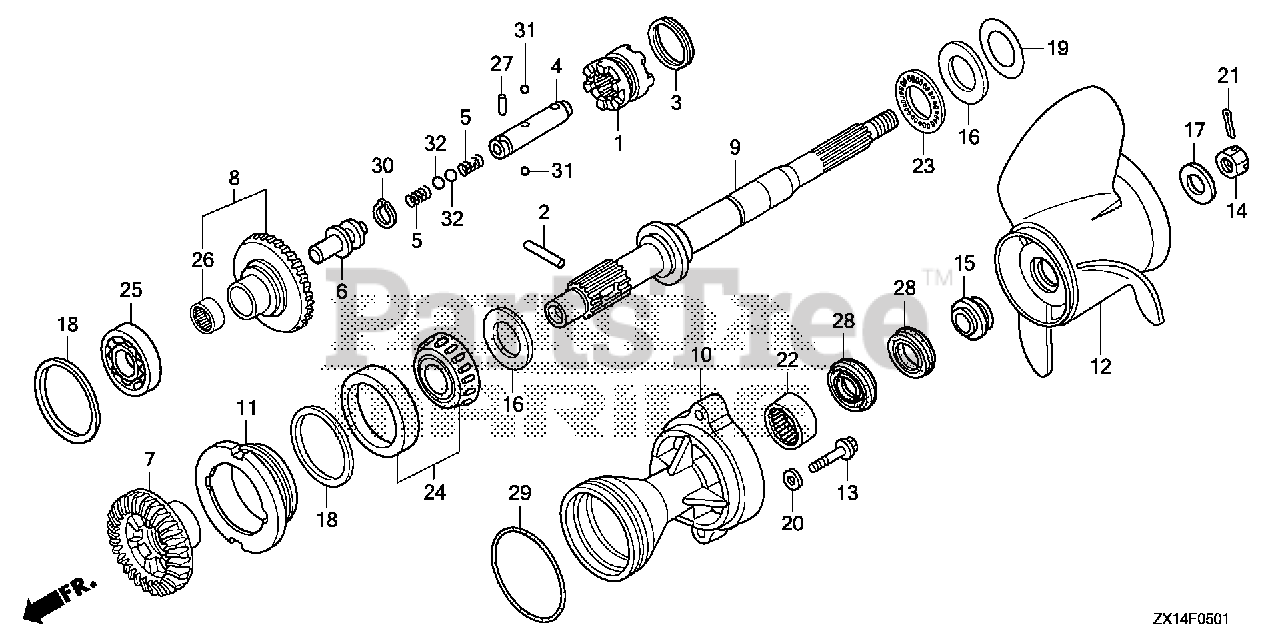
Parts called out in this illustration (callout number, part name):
1	SHIFTER, CLUTCH
2	PIN, SHIFTER (8X47)
3	RING, CROSS PIN
4	SLIDER, SHIFT
5	SPRING, SHIFT
6	PLATE, SHIFT
7	GEAR, BEVEL (FORWARD 30T) (COUNTER ROTATION)
8	GEAR, BEVEL (RVS. 30T) (COUNTER ROTATION)
9	SHAFT, PROPELLER (COUNTER ROTATION)
10	HOLDER, PROPELLER SHAFT *NH282MU* (OYSTER SILVER METALLIC-U)
11	HOLDER, BEARING (COUNTER ROTATION)
12	PROPELLER, THREE-BLADE (14-1/2X15) (C/R)
12	PROPELLER, THREE-BLADE (14-1/4X17) (C/R)
12	PROPELLER, THREE-BLADE (14X19) (C/R)
12	PROPELLER, THREE-BLADE (14X21) (C/R)
12	PROPELLER, THREE-BLADE (14-1/2X23) (C/R)
13	BOLT, FLANGE (10X40)
14	NUT, CASTLE (18MM)
15	WASHER, PROPELLER THRUST
16	WASHER, THRUST BEARING
17	WASHER, PROPELLER
18	SHIM A, BEVEL (0.10)
18	SHIM B, BEVEL (0.15)
18	SHIM C, BEVEL (0.30)
18	SHIM D, BEVEL (0.50)
19	SHIM A, THRUST (0.10)
19	SHIM B, THRUST (0.15)
19	SHIM C, THRUST (0.30)
19	SHIM D, THRUST (0.50)
20	WASHER, PLAIN (10MM)
21	PIN, SPLIT (4.0)
22	BEARING, NEEDLE (30X37X26)
23	BEARING, THRUST (F)
24	BEARING, TAPER (50X90X28)
25	BEARING, RADIAL BALL (50X90X20)
26	BEARING, NEEDLE (25X32X26)
27	ROLLER (3X12.8)
28	SEAL, WATER (30X45X7)
29	O-RING (105X3.1)
30	CIRCLIP, OUTER (14MM)
31	BALL, STEEL (#7) (7/32)
32	BALL, STEEL (#9) (9/32)
